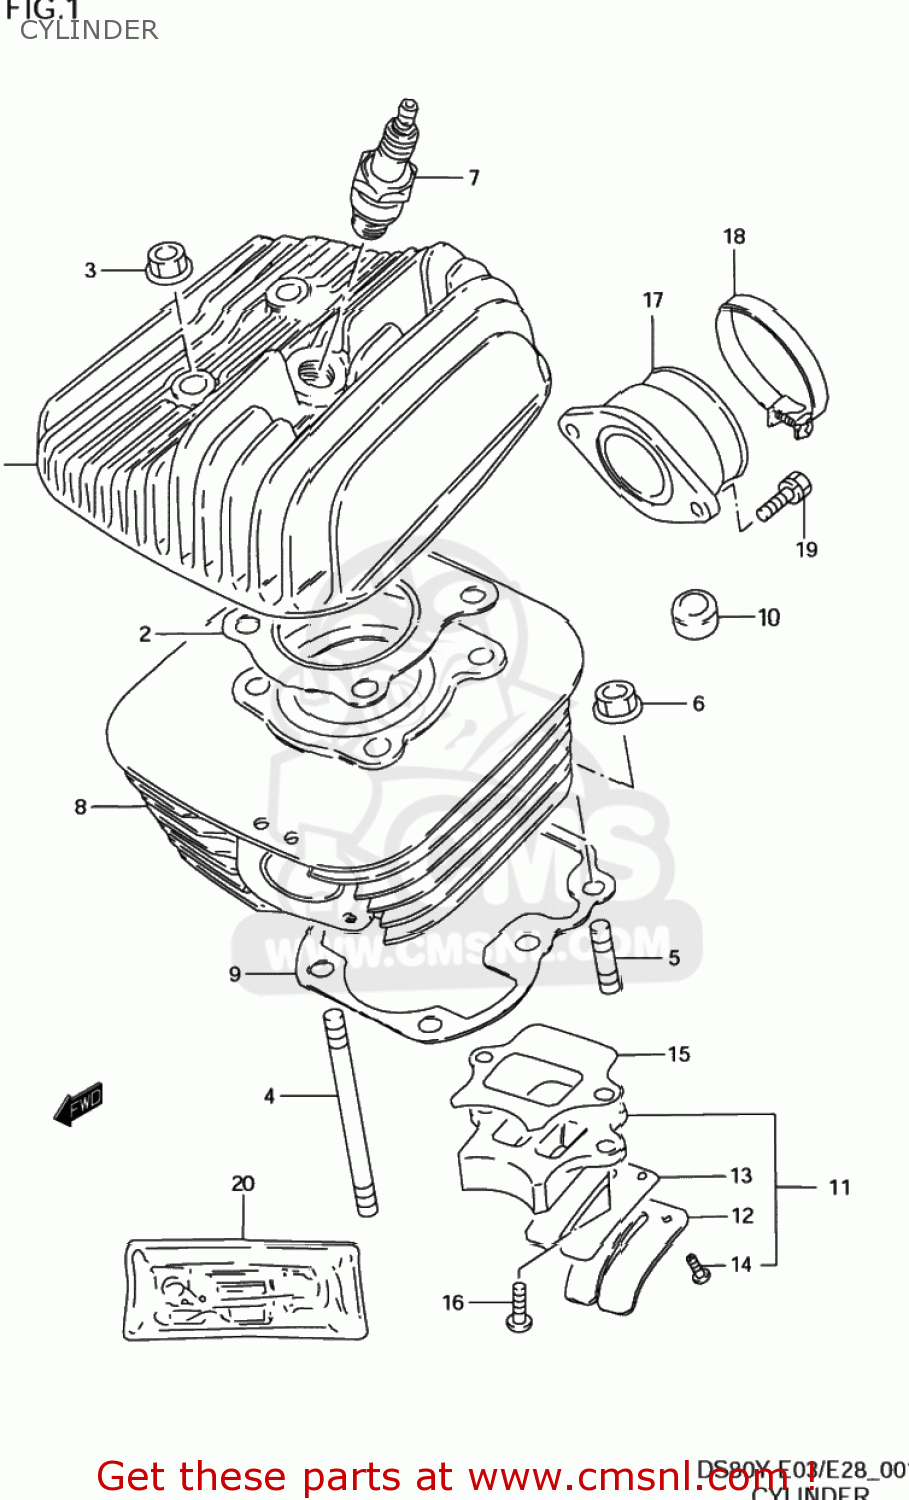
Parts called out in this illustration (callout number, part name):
1	HEAD,CYLINDER
2	GASKET,CYLINDER HEAD (NAS)
3	NUT
4	BOLT,STUD
5	STUD 6X20
6	NUT
7	PLUG,SPARK(BR7ES)
8	CYLINDER
9	GASKET,CYLINDER (NAS)
10	PAD,CYLINDER RUBBER(N1)
11	VALVE ASSY,REED
12	STOPPER,REED VALVE
13	VALVE,REED
14	SCREW
15	GASKET,REED VALVE (NAS)
16	SCREW 6X16
17	PIPE,INTAKE
18	CLAMP
19	BOLT
20	GASKET SET (NAS)
